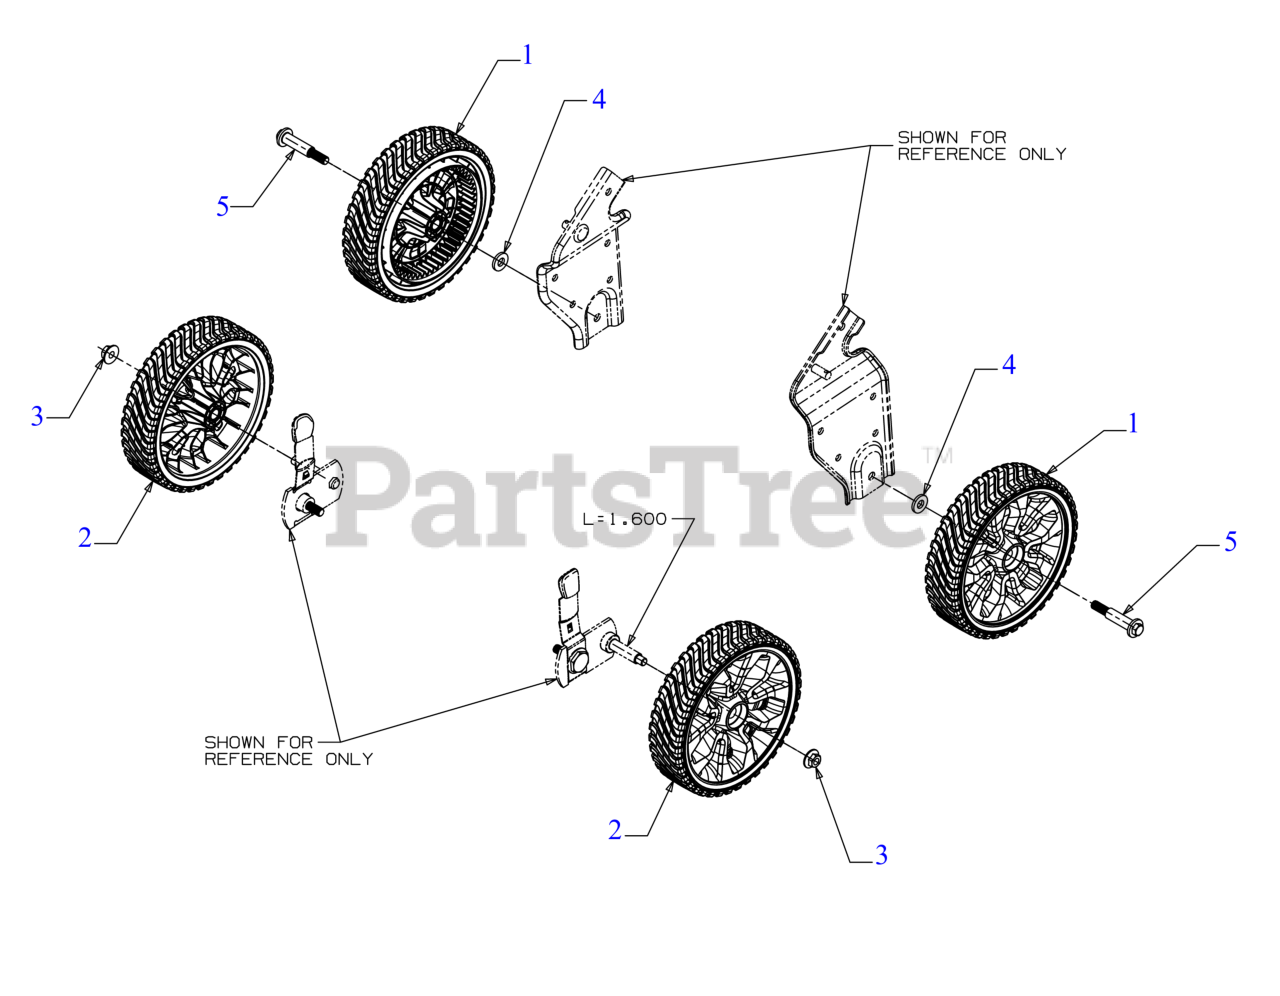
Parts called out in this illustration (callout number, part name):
1	DRIVE WHEEL ASSEMBLY 8X2
2	WHEEL ASSEMBLY 8 x 2 GRAY
3	FLANGE LOCK NUT
4	FLAT WASHER
5	SHOULDER SCREW .496X1.605 3/8-16
